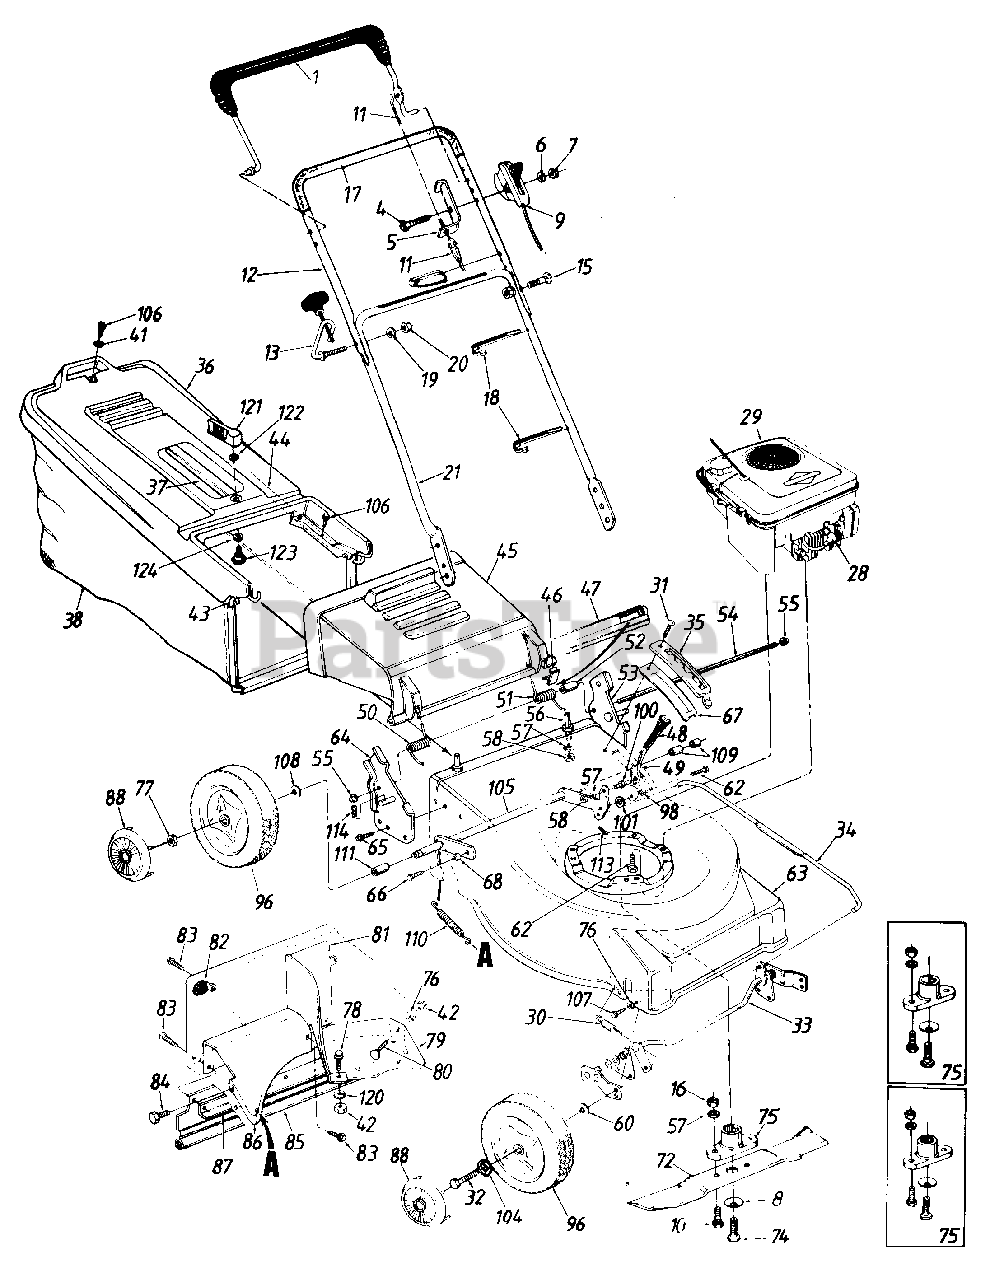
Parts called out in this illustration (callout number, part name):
1	Control Handle
4	Hex Bolt 1/4-20 x 1.75" Lg.
5	Cable Brkt.
6	Spr. Wash. 1/4" I.D.
7	Hex Nut 1/4-20 Thd.
8	Bell-Wash. .39" I.D.
9	Throttle Control Ass'y. Comp.- 43.62"
10	Hex Bolt 3/8-24 x 1" Lg.
11	Control Cable-55"
15	Curved Carriage Bolt 5/16-18 x 1.38" Lg.
16	Hex Nut 3/8-24 Thd.
17	Foam Grip
18	Cable Tie
19	L-Wash. 5/16" I.D.
20	Hex Nut 5/16-18 Thd.
21	Lower Handle
28	Spark Plug Boot
29	Engine
30	Extension Spring 2.39" Lg.
31	Torx Hd. AB-Tap Scr. 1/4"-.62" Lg.
32	Axle Bolt
34	Height Adj. Connecting Rod
35	Height Adjustment Plate
36	Hardtop Bag Cover
37	Hardtop Handle
38	Grass Bag
41	Fl-Wash. .281" I.D. x .62" O.D.
42	Hex Nut 1/4-20 Thd.
43	Front Catcher Frame
44	Rear Catcher Frame
45	Chute Deflector
46	Deflector Plug
47	Seal-Extrusion
49	Spring Lever
50	Torsion Spring-R.H.
51	Torsion Spring-L.H.
52	Spacer.255" I.D.
53	Handle Brkt. Ass'y.-L.H.
54	Hinge Pin 17.75" Lg.
55	Cap Speed Nut
56	Shld. Pin 3/8-24 x 1.43" Lg.
57	L-Wash. 3/8" I.D.*
58	Hex Jam Nut 3/8-24 Thd.
60	Bell-Wash. .38" I.D. x .88" O.D.
62	Hex L-Wash. Hd. Scr. 3/8-16 x 1 " Lg .
63	21" DeckAss'y.
64	Handle Brkt. Ass'y.-R.H.
65	Hex L-Wash. Hd. AB-Tap Scr. 1/4 x.62" Lg.
66	Hex Wash. Hd. Tap Scr. 3/8-16 x .75" Lg.
67	Height Adjustment Support
68	Spacer.385" I.D.
72	21" Blade
74	Hex Bolt 3/8-24 x 1.5" Lg.
75	Blade Adapter Kit (Keyed)
76	L-Wash. 1/4" I.D.
77	Hex Jam Nut 1/2-20 Thd.
78	Hex Bolt 1/4-20 x .85" Lg.
79	Rear Belt Baffle
80	Carr. Bolt 1/4-20 x .50" Lg.
83	Torx Mach. AB-Tap Scr. 1/4 x .62" Lg.
84	Hex B-Tap Scr. 1/4 x .381 Lg.
85	Rear Flap
96	Wheel Ass'y. Comp.
98	Shld. Spacer .50" Dia.
100	Shld. Pin 3/8-24 x 1.43" Lg.
101	Fl-Wash. .375" I.D. x 1.0"
104	Wave Wash. 53" I.D. x 78"
105	Rear Axle Ass'y.
106	Hex L-Wash. AB-Tap Scr. 1/4 x 62" Lg.
107	Hex L-Wash. HD AB-Tap Scr. 1/4 x .38" Lg.
108	Fl-Wash. .510" I.D. x .75"
109	Spacer. 526" I.D.
110	Extension Spring 88" Lg.
111	Sleeve.526" I.D.
113	Cotter Pin 3/32" Dia. x 75"
114	Internal Cotter Pin 5/16" Dia.
120	Bell-Wash. 1/4" I.D.
121	Grass Catcher Locking Knob
122	Internal L-Wash. 1/4" I.D.
123	Shld. Bolt .342" Dia. x .268
124	Wave Washer 3/8" I.D.
